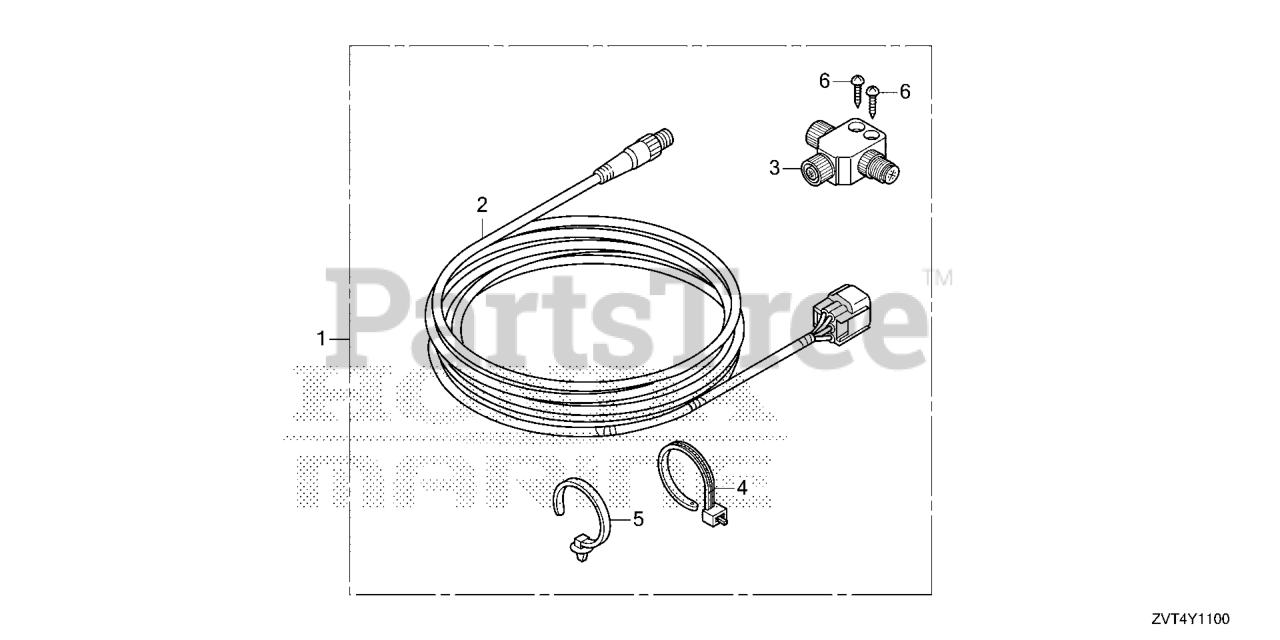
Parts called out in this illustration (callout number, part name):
1	CABLE KIT, INTERFACE
2	CABLE ASSY., INTERFACE (10FT)
2	CABLE ASSY., INTERFACE (16FT)
2	CABLE ASSY., INTERFACE (6FT)
3	CONNECTOR (T)
4	TIE, CABLE
5	CLIP, HARNESS BAND (155.3MM) (BLACK)
6	SCREW, TAPPING (4X25)
